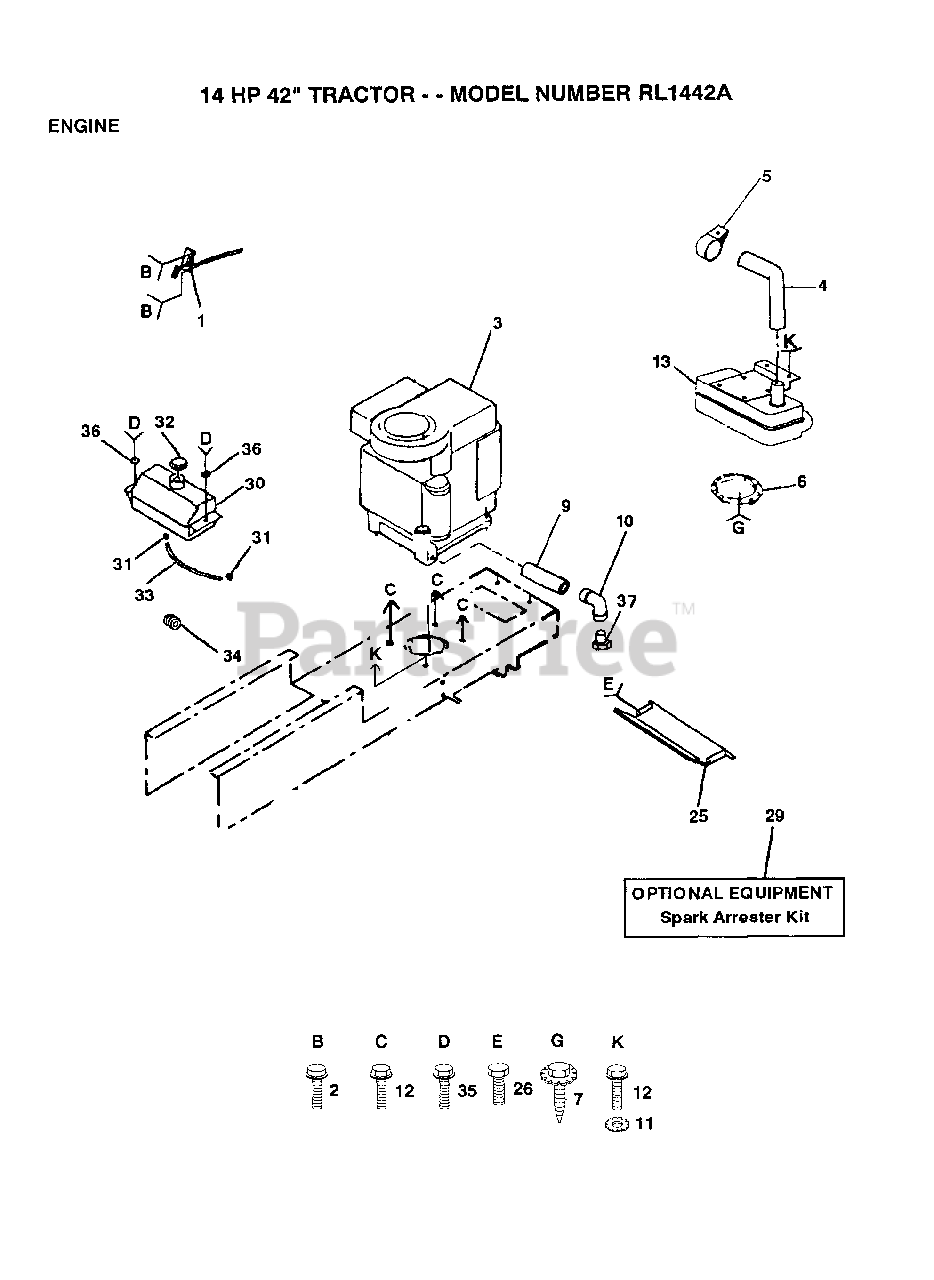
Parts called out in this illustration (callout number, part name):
2	SCREW LT
4	"TUBE,EXHAUST"
5	"CLAMP,MUFFLER"
6	DEFLECTOR.222573
9	PIPE NIPPLE
10	ELBOW
11	LOCKWASHER
12	SCREW
25	HEAT SHIELD
26	SCREW
29	SPARK ARREST KIT
30	TANK.FUEL.LT.
31	HOSE CLAMP
33	FUEL LINE T
35	SCREW HEX CRT
36	WASHER
